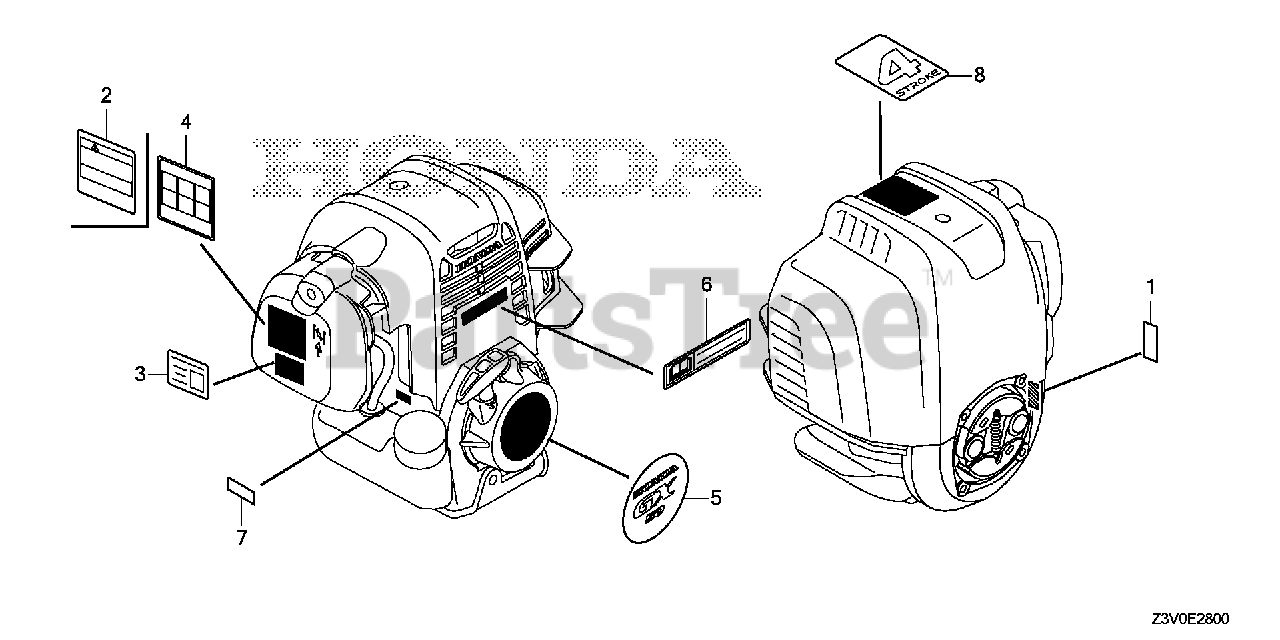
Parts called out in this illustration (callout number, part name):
1	LABEL, WARNING (NOT CERTIFIED FOR SALE)
3	LABEL, QR CODE (SERVICE)
4	MARK, OPERATOR CAUTION (PICTOGRAPH)
5	MARK, EMBLEM
7	MARK, TYPE (STSC)
8	MARK (4-STROKE)
